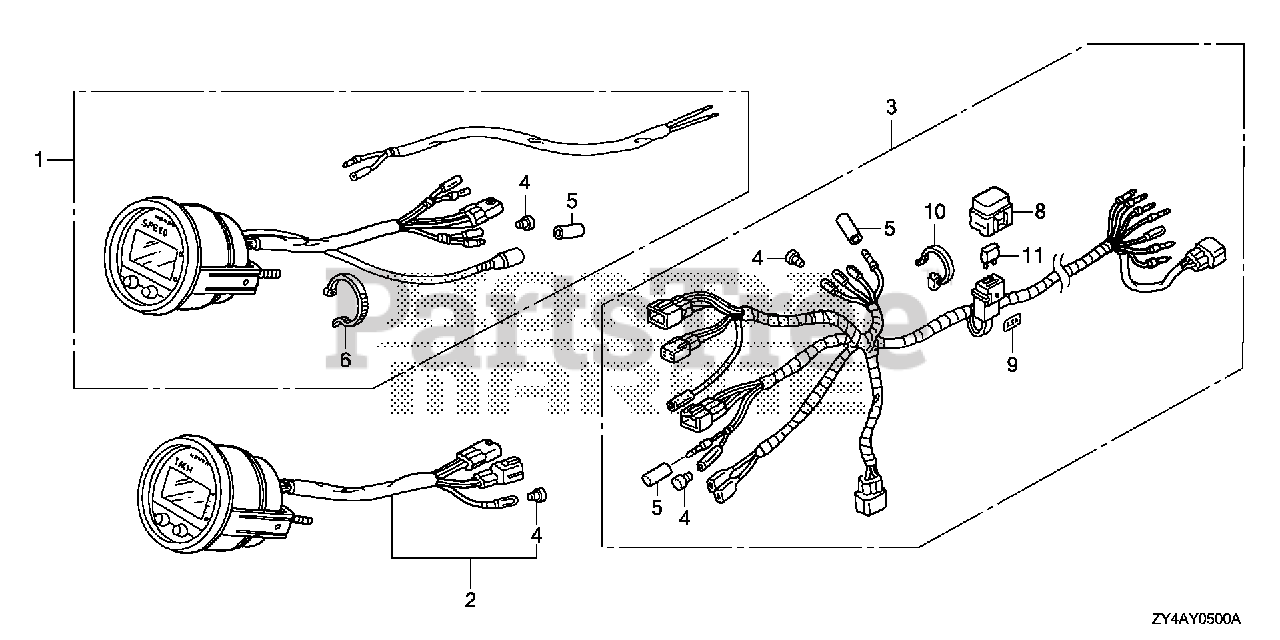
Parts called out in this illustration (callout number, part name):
1	SPEEDOMETER KIT (DIGITAL)(USA) (NOT AVAILABLE)
2	METER KIT, TACHO (DIGITAL) (USE FOR 32540-ZY3-800/801)
3	HARNESS ASSY., METER (A)(DIGITAL)
4	PLUG, CONNECTOR (INNER)
5	PLUG, CONNECTOR (OUTER)
6	BAND (BLACK 3.5X140)
8	COVER ASSY., FUSE (7.5A)
9	MARK, FUSE (7.5A)
10	TIE, CABLE
11	FUSE, BLADE (7.5A)
